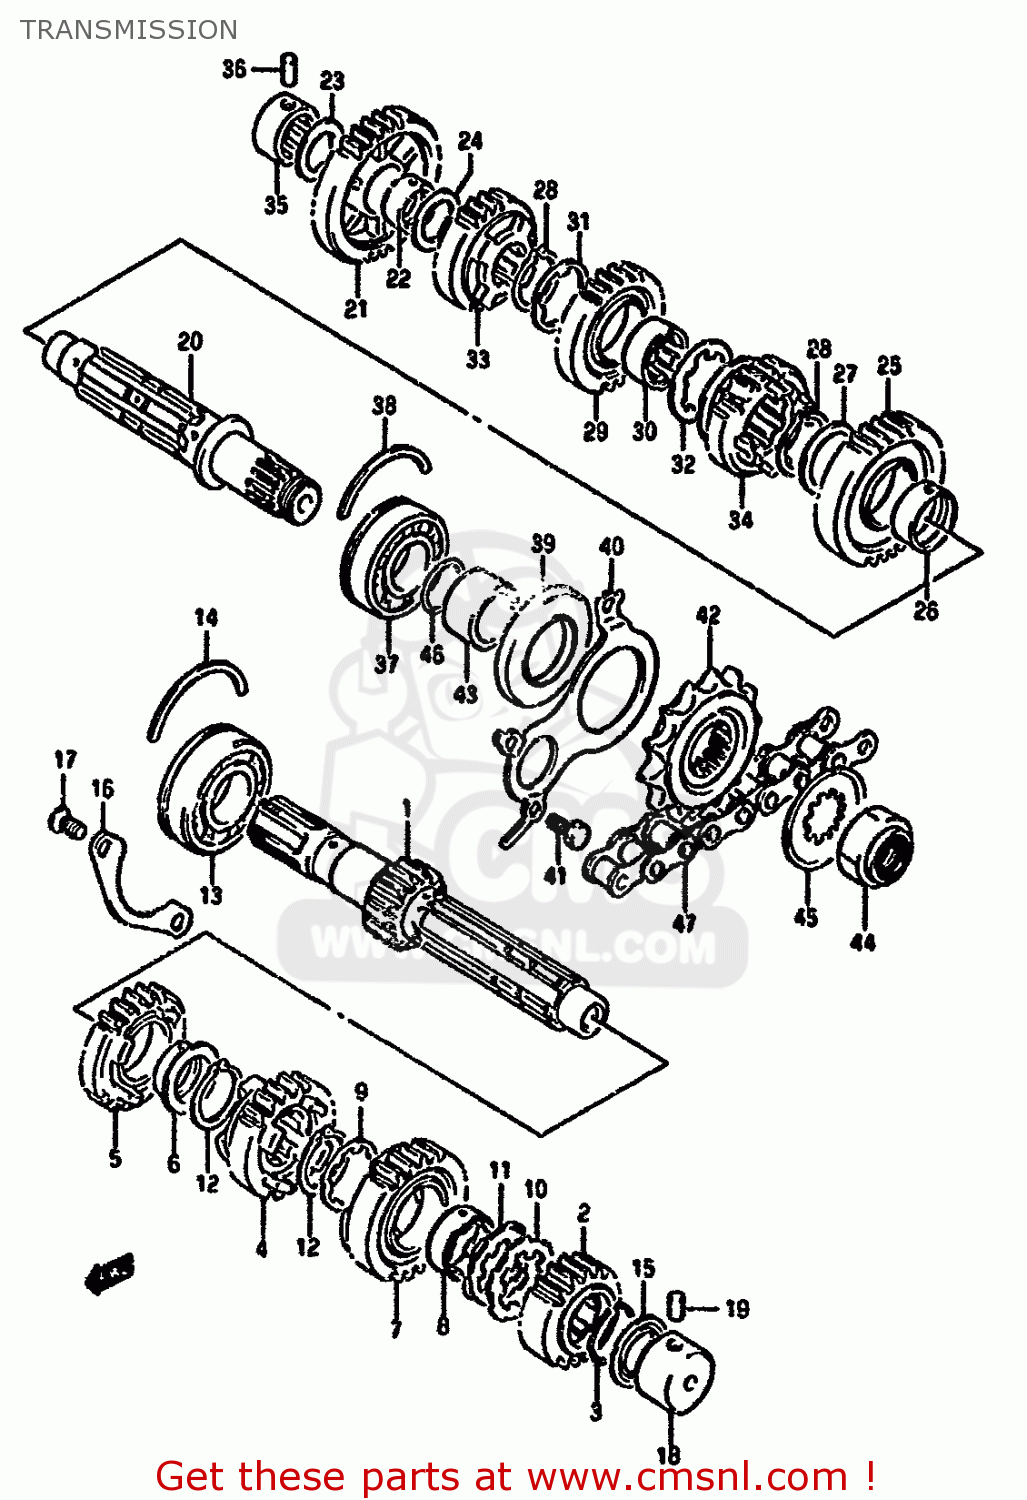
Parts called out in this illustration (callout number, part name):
1	SHAFT,COUNTER
2	GEAR,2ND DRIVE(NT:19)
3	CIRCLIP
4	GEAR,THIRD DRIVE (NT:20)
5	GEAR,FOURTH DRIVE (NT:22)
6	BUSHING
7	GEAR,FIFTH DRIVE (NT:23)
8	BUSH,5TH DRIVE GEAR
9	WASHER,LOCK
10	WASHER,LOCK
11	WASHER
12	RING,SNAP
13	BEARING(25X62X17)
14	C-RING
15	SEAL,OIL(20X31.2X2.7)
16	RETAINER,CNTR SHAFT BEARING
17	SCREW
18	BEARING(20X34X17.5)
19	PIN
20	SHAFT,DRIVE
21	GEAR,FIRST DRIVEN
22	BUSHING
23	WASHER
24	WASHER
25	GEAR,SECOND DRIVEN
26	BUSH(28X32X11)
27	WASHER
28	CIRCLIP
29	GEAR,THIRD DRIVEN
30	BUSHING,THIRD DRIVEN GEAR
31	WASHER,LOCK
32	WASHER,LOCK
33	GEAR,FOURTH DRIVEN (NT:23)
34	GEAR,FIFTH DRIVEN
35	BEARING(20X34X20)
36	PIN
37	BEARING(25X62X19)
38	C-RING
39	SEAL,OIL(34X62X6)
40	RETAINER,DRIVE SHAFT OIL SEAL
41	BOLT
42	SPROCKET,ENGINE(15T)
43	SPACER (25X34X19.7)
44	NUT
45	WASHER,LOCK
46	O RING(D:1,ID:24.5)
47	CHAIN ASSY
